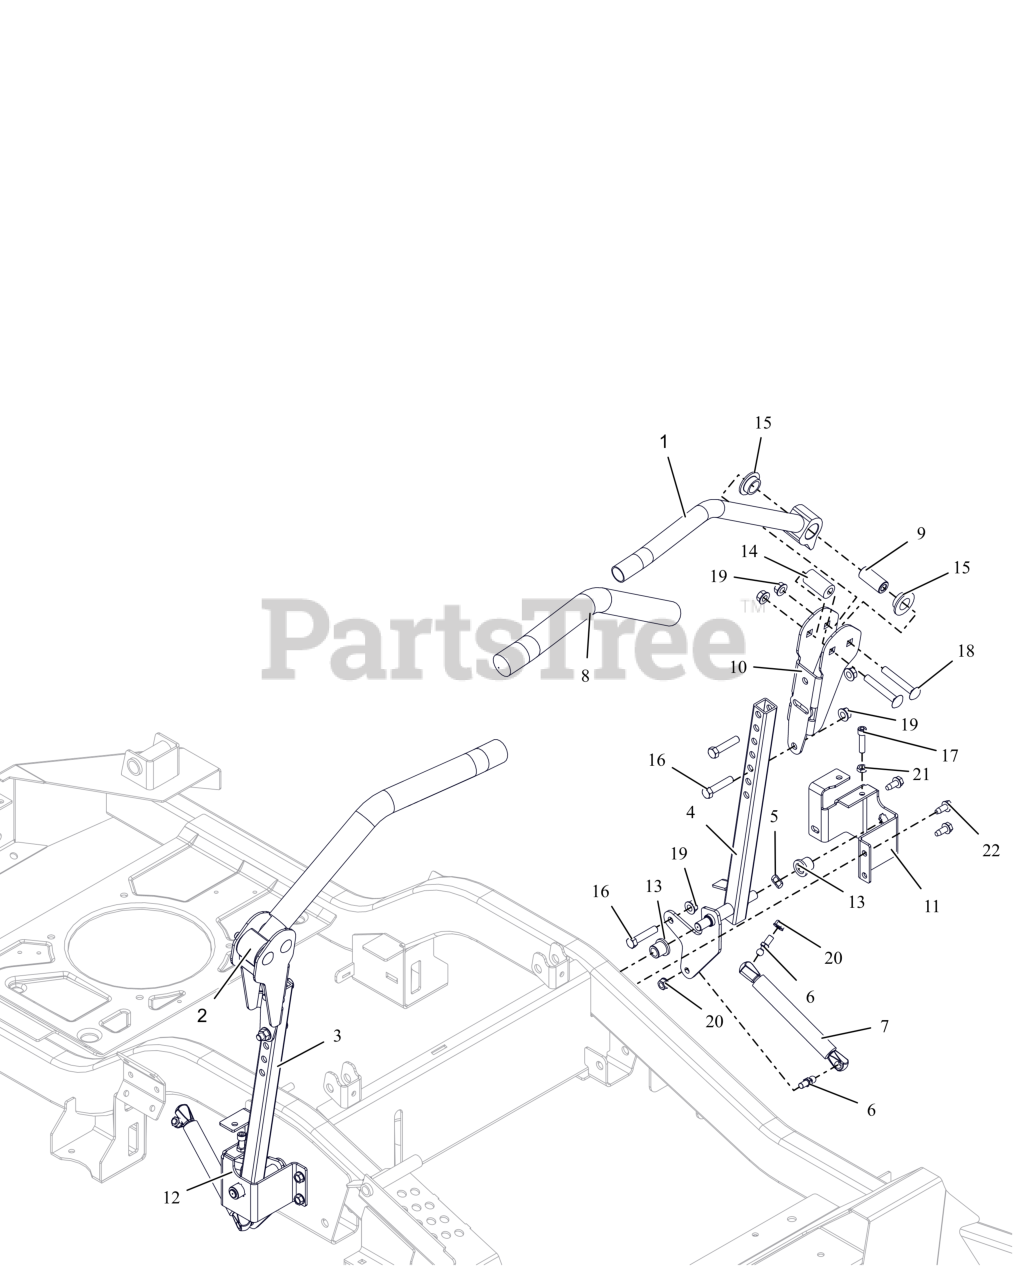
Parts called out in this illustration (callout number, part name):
1	WLDMT, CONTROL HANDLE-LH (BLACK)
2	WLDMT, CONTROL HANDLE-RH (BLACK)
3	WLDMT, STEERING RH
4	WLDMT, STEERING LH
5	WAVE WASHER .531X.781X.125FH
6	STUD- BALL
7	DAMPER
8	GRIP, HANDLEBAR
9	SPACER, STEERING ARM
10	ADJ UPPER CONTROL ARM BRKT-BLK
11	BRKT, STEERING ARM MOUNT -LH
12	BRKT, STEERING ARM MOUNT -RH
13	BHSG-FLG .500X.750X.750X.125
14	BSHG, ECCENTRIC.406X.875X1.625
15	BSHG-FLG .762X1.48X.44 NYL
16	BLT, HEX .38-16X1.75 G5 ZCC
17	BLT, SHCS .312-18X1.25 G8 SS
18	BLT, RHSSN.38-16X2.50 G5 ZCC
19	NUT-LK-TOP-FLG .38-16 ZC120
20	NUT,LK-CTR-FLG .31-18 GF ZCC
21	NUT-JAM .312-18 G2 ZCC
22	SCR,TAP .312-18X.75 HWH TR ZCC
